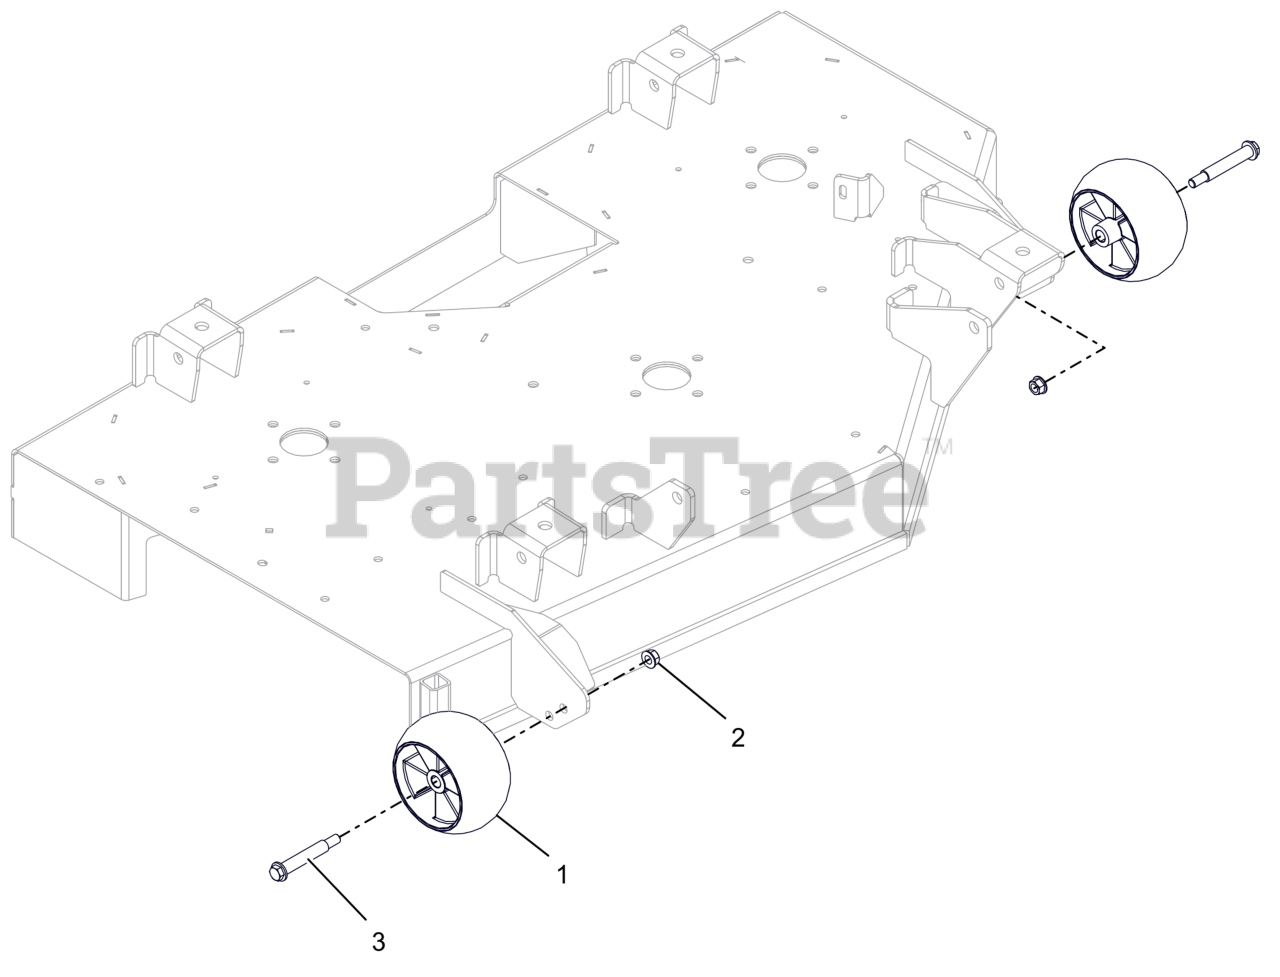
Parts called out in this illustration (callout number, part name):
1	ANTI-SCALP WHEEL - 5X OS
2	NUT-LK-CTR-FLG .375-16 GF ZCC
3	BLT-SHLDR .38-16X2.50 HWH G5
